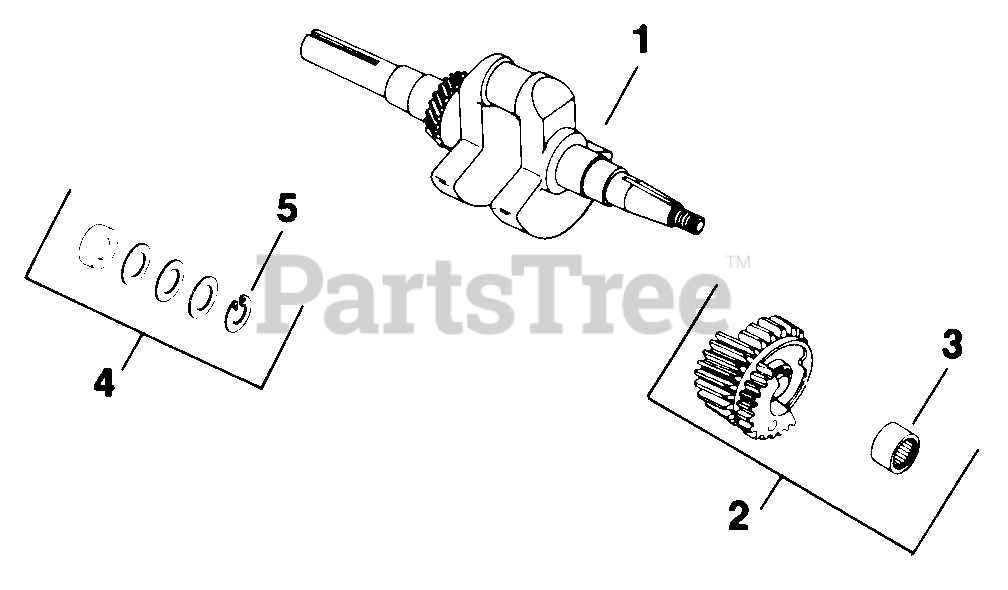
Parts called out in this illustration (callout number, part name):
1	CRANKSHAFT - USE 47 142 26
1	CRANKSHAFT KIT-USE 45 142 22-S
2	GEAR - USE 45 043 03
3	BEARING
4	KIT, SPACER
